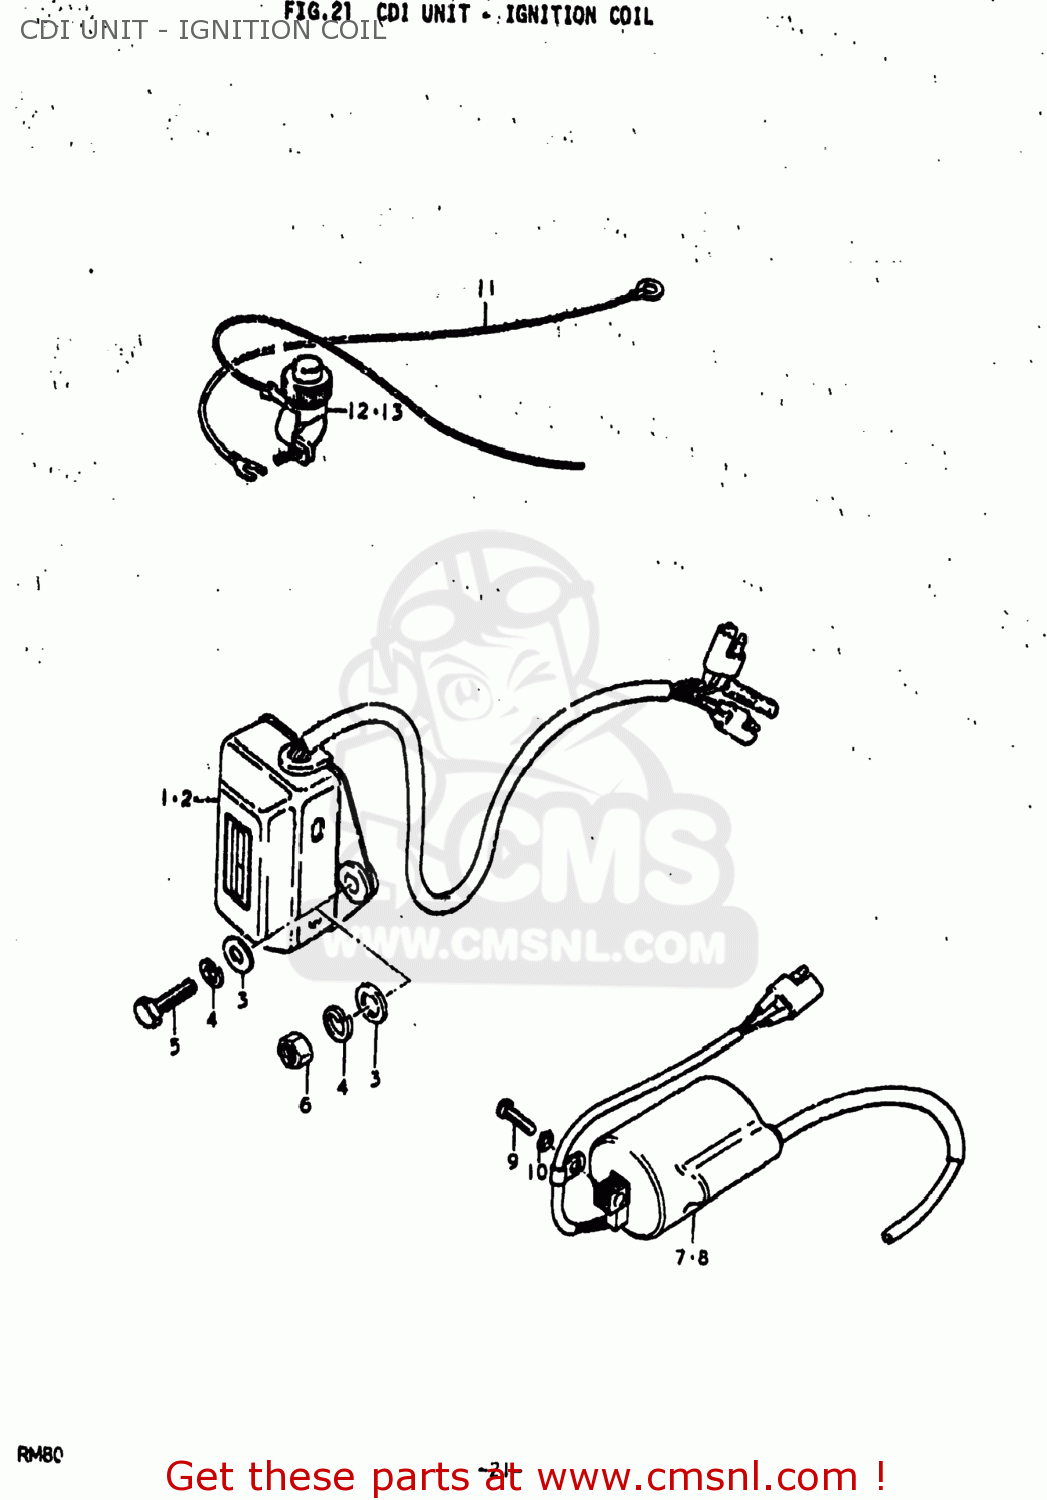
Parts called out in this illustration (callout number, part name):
1	CDI UNIT ASSEMBLY
2	CDI UNIT
3	WASHER(6.5X16X1.2)
4	LOCK WASHER
5	BOLT
6	NUT
7	COIL ASSY,IGNITION
8	COIL ASSEMBLY,IGNITION
9	SCREW 5X20
10	LOCK WASHER
11	WIRE,ENGINE STOP EARTH
12	SWITCH ASSEMBLY
13	SWITCH ASSEMBLY
